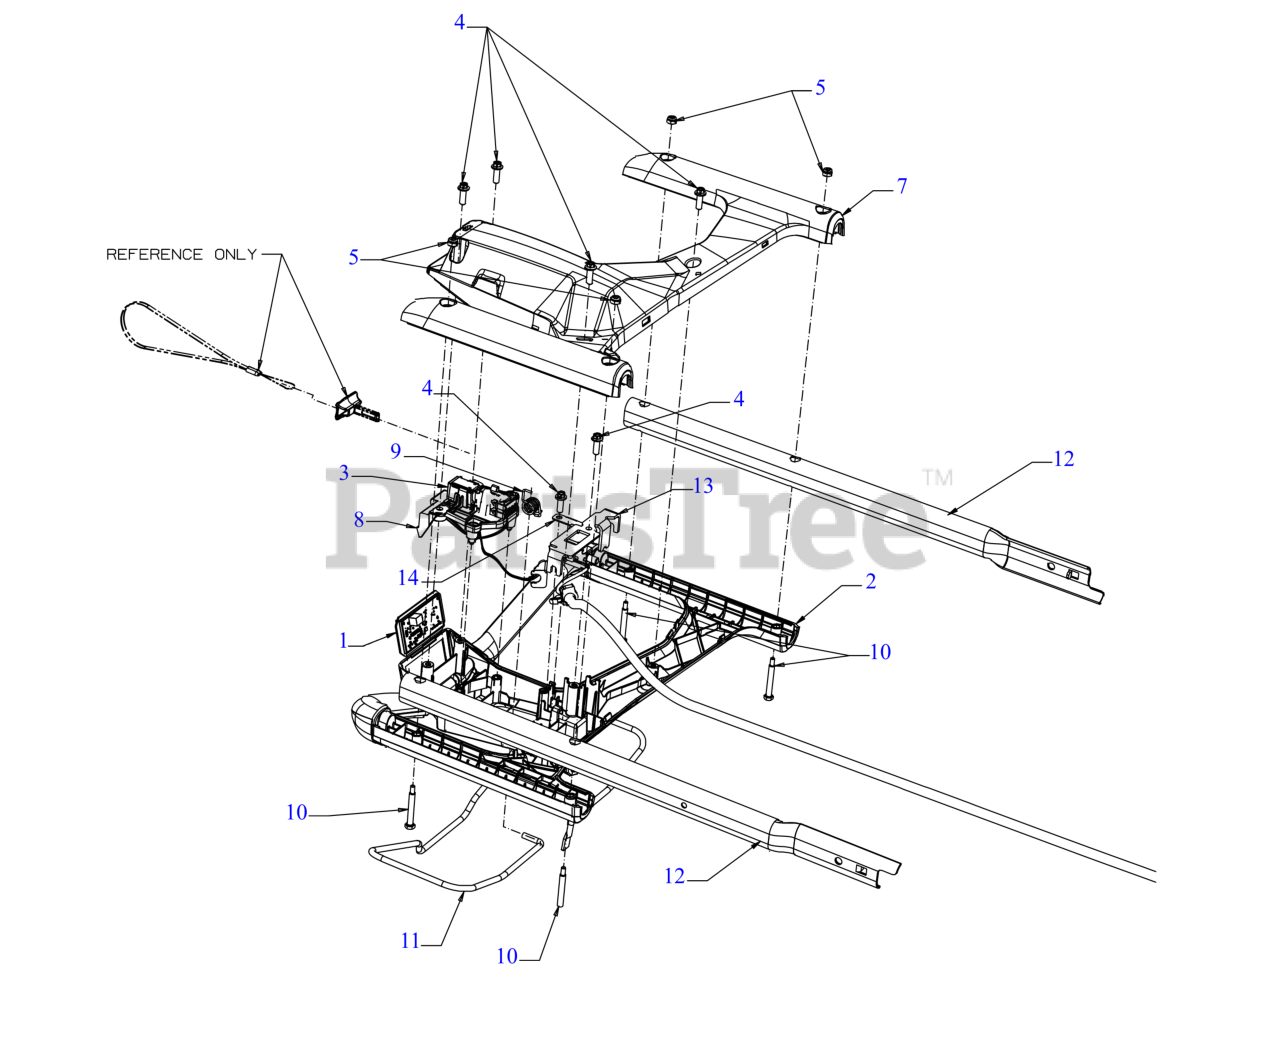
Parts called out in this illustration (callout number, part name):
1	BATTERY DISPLAY (60V)
2	PANEL (UPPER)
3	KEY RECEPTACLE
4	SCREW 1/4 x .750
7	HANDLE PANEL (LOWER)
8	PUSH KEY RECEPTACLE BRACKET
9	TORSION SPRING
10	SHOULDER SCREW .25:1.63:#10-24:.32
11	OPERATOR BAIL (ERGO)
12	HANDLE (UPPER)
13	BAIL SUPPORT BRACKET
14	BAIL SWITCH BRACKET
